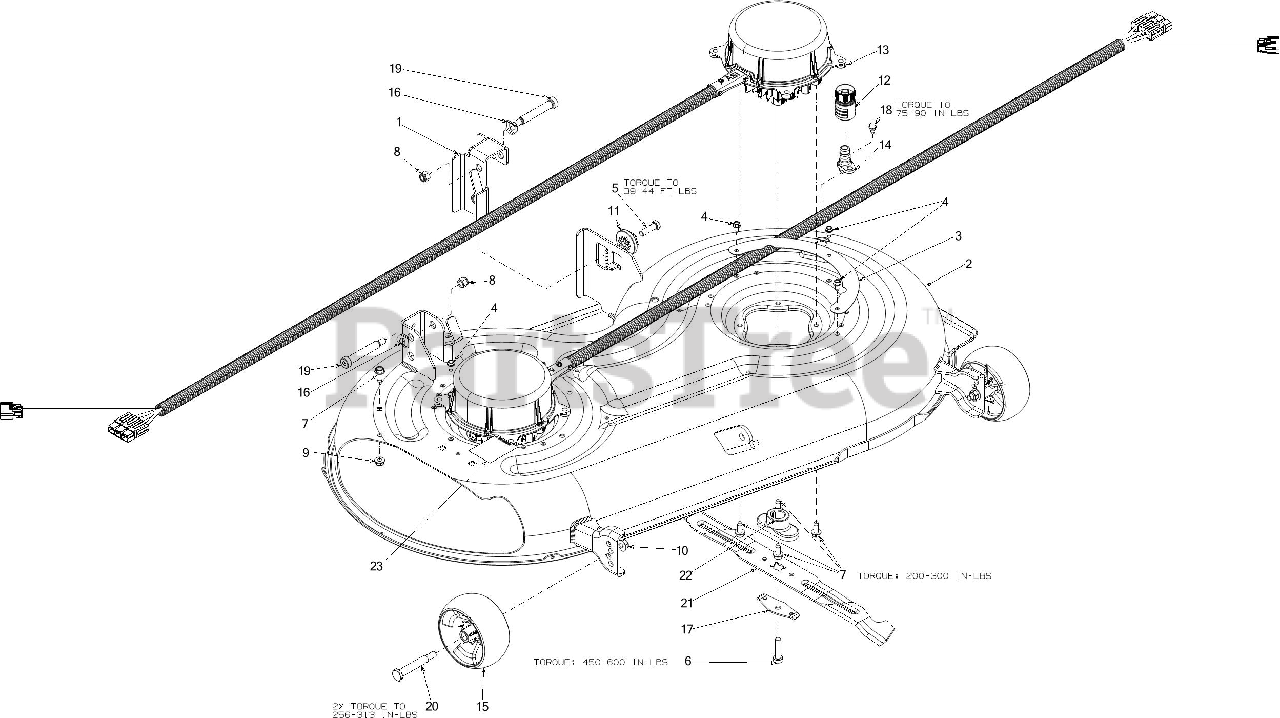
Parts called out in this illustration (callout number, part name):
1	DECK HANGER BRACKET (LH)
2	42" DECK SHELL E
3	ELECTRIC DECK COVER
4	SCREW 1/4-20 X.500
5	SCREW 3/8-16 x 1.25 GR5
6	SCREW 3/8-24 x 1.50 GR8
7	SCREW 5/16-18 x .750
8	HEX NUT INS L-3/8-16
9	FLANGE LOCK NUT 5/16-18
11	DECK ADJUSTMENT GEAR
12	WATER NOZZLE
14	DECK WASH NOZZLE
15	DECK WHEEL
16	SPRING WASHER .50 x 1.0 x .022
17	BLADE BELL SUPPORT
18	SHOULDER SCREW 1/4-20 x .50
19	SHOULDER BOLT .500 x 2.75 x 3/8-16
20	SHOULDER BOLT
21	21.18" BLADE (MULCH)
22	BLADE ADAPTER-W/STAR
23	LABEL (NOT SERVICEABLE)
